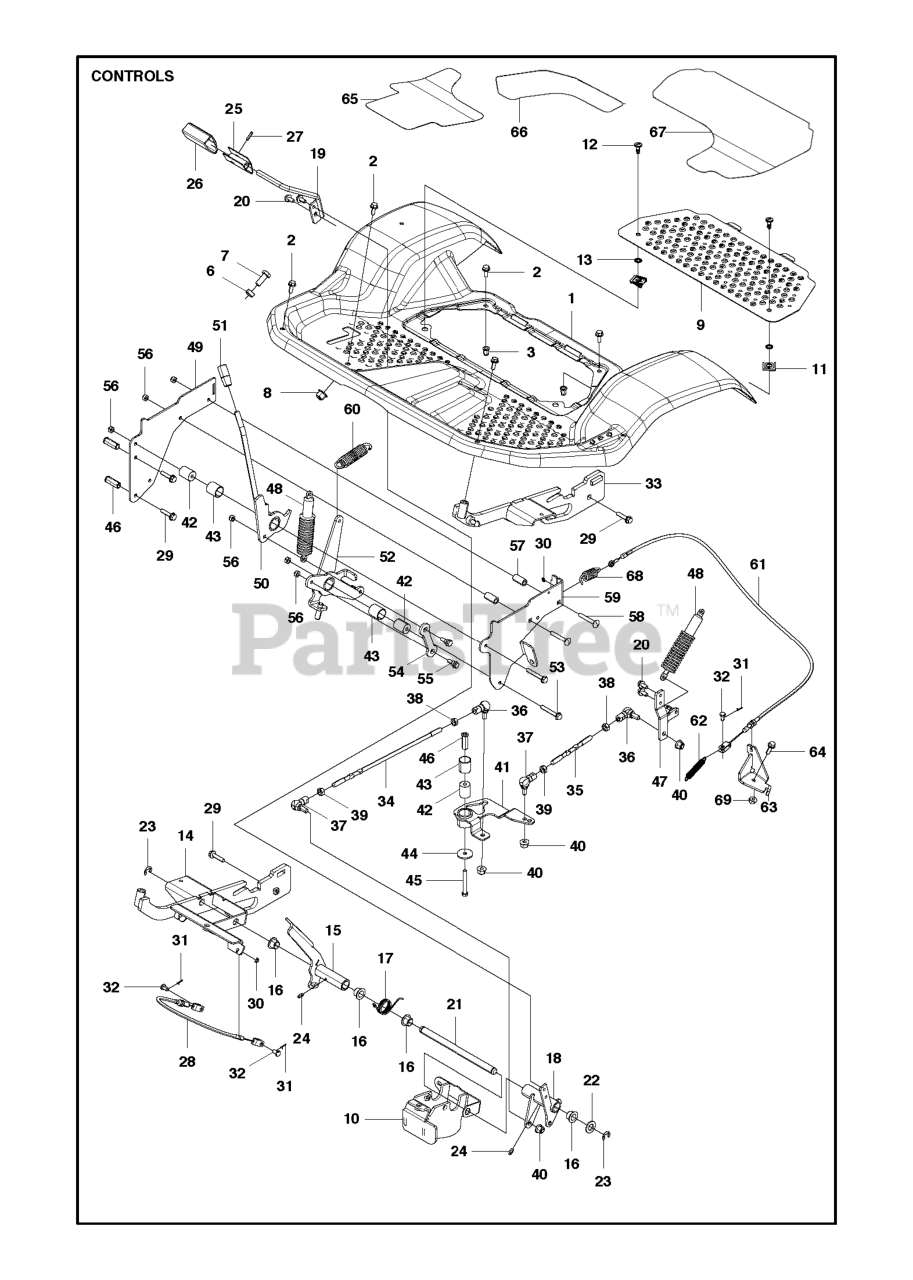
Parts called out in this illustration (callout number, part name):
7	Hex Head Capscrew, M12 X 1.75 X 30 DIN933ZP
16	BUSHING
20	BOLT
24	GREASE NIPPLE
26	PEDAL RUBBER
29	SCREW EHHFM
31	Cotter Pin
32	Clevis Pin
43	BUSHING
48	SHOCK ABSORBER
53	SCREW EHHFM
56	LOCKNUT M8
64	BOLT
68	SPRING
69	NUT FLANGE
